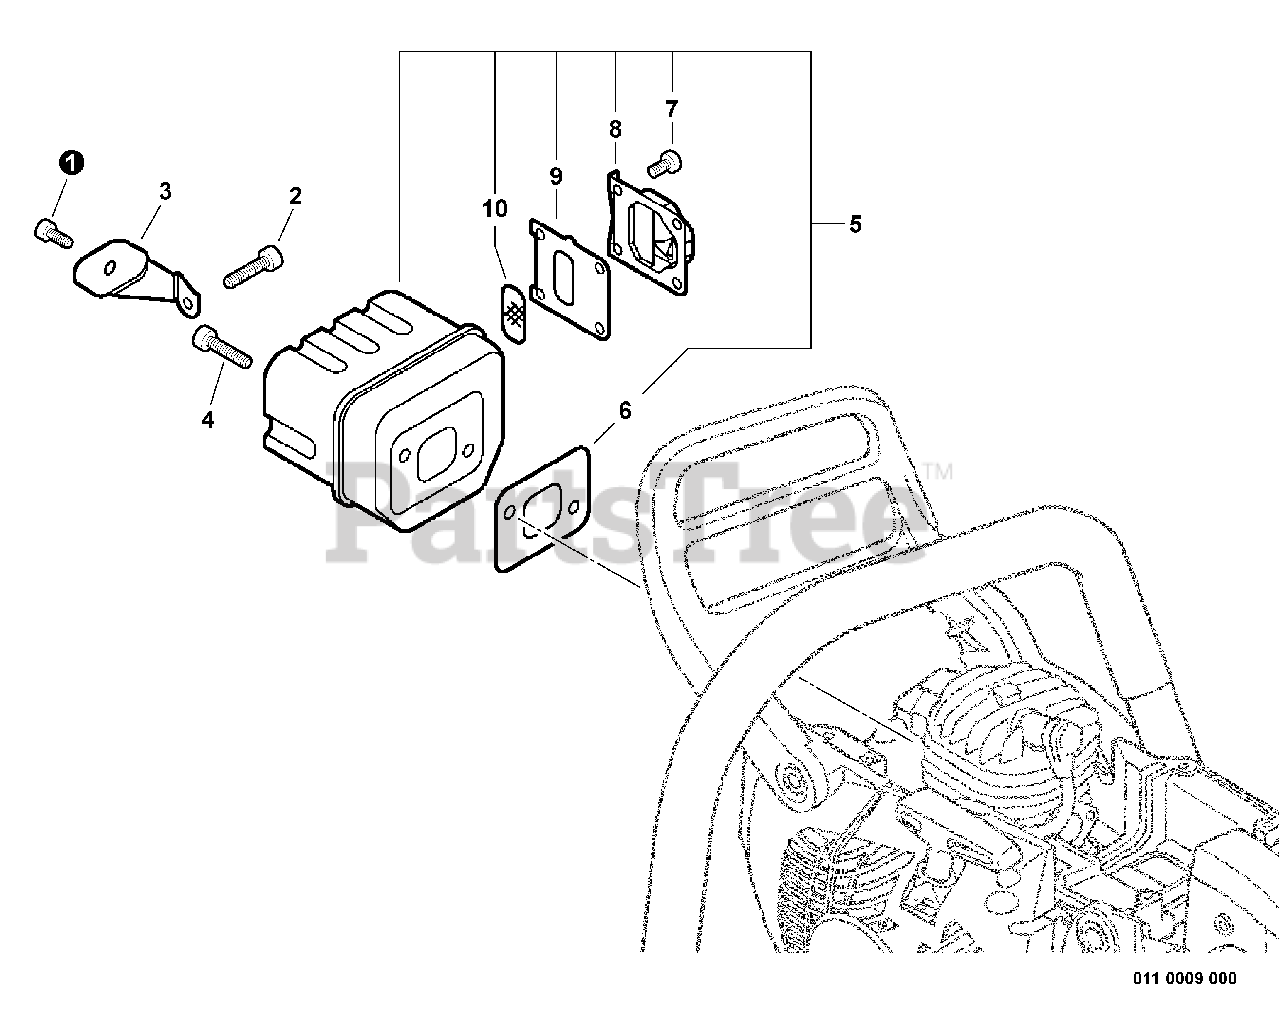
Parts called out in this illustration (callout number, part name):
2	SCREW - 6X14
3	BRACKET, MUFFLER
4	SCREW - 5X16
5	MUFFLER ASSY
6	GASKET, EXHAUST
7	SCREW - 4X10
8	GUIDE, EXHAUST
9	GASKET, EXHAUST
10	SCREEN, SPARK ARRESTOR
